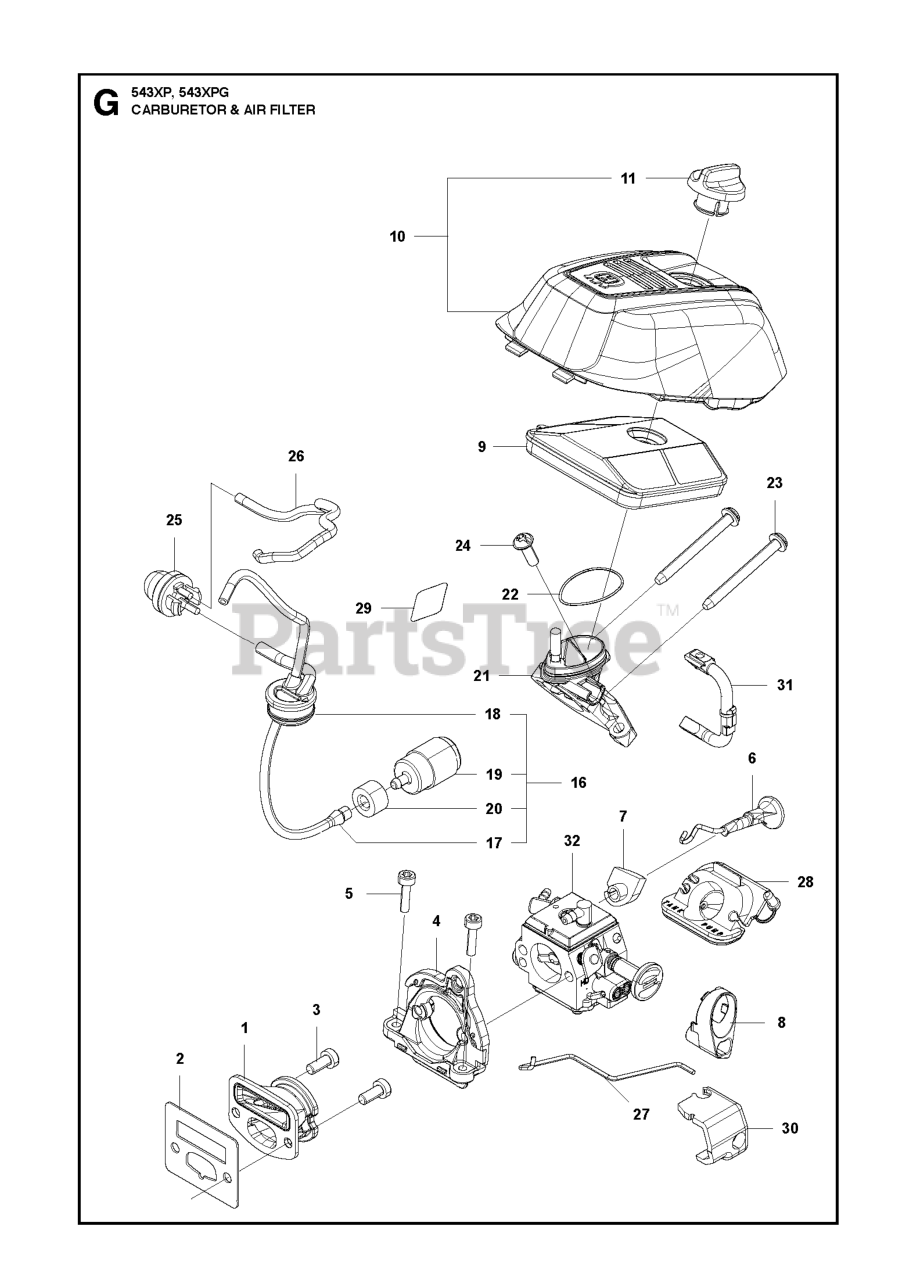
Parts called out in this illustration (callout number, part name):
1	INLET PIPE ASSY
3	BOLT
4	FLANGE ASSY
5	BOLT
6	ROD CHOKE XC25
8	GROMMET ID
9	CLEANER
9	CLEANER COMP
10	AIR FILTER COVER
16	Fuel Hoses
17	FUEL PIPE
19	FILTER ASSY
21	MANIFOLD
22	O-RING
22	SEAL MANIFOLD
24	SCREW M5 X 14
25	PRIMARY BTN
26	Fuel Hoses
27	THROTTLE ROD
30	GROMMET CARB
31	PIPE COMPENSATOR ASSY
32	CARBURETTOR
32	CARBURETTOR ASSY
32	CARBURETTOR ASSY HD
